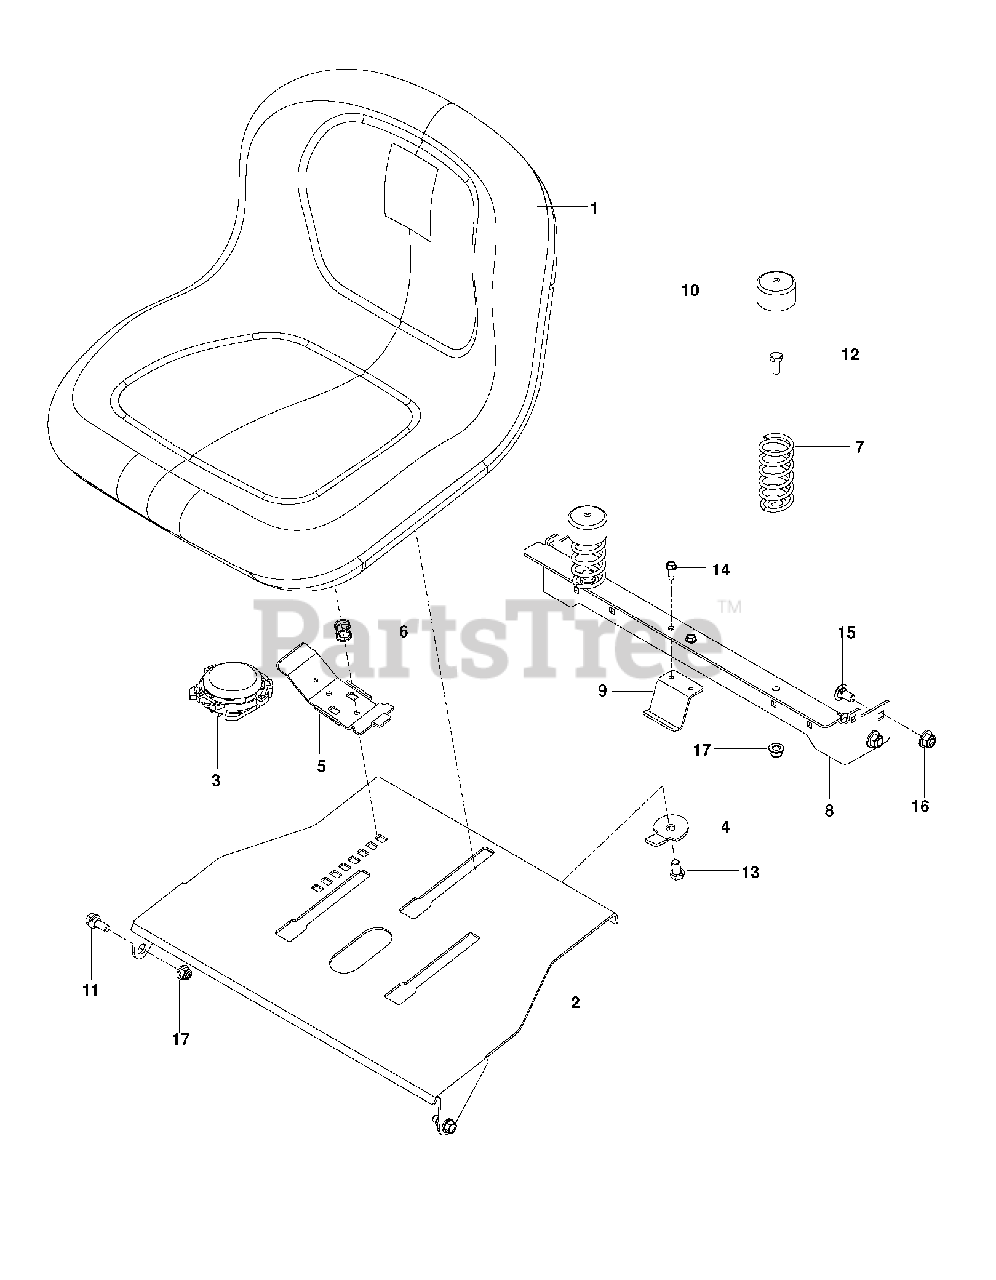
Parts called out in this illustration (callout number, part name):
1	SEAT.TH150.MS498.GRY.HUSQ.TEX
2	PLATE, SEAT, ORG
3	SWITCH, SEAT N/C
4	STOP, SEAT, BLACK
5	HANDLE.SLIDE.SEAT.TEX.BLACK
6	SPRING.LATCH.SEAT.TEX
7	SEAT SPRING
8	SEAT SUPPORT, REAR ORG
9	HOLDING DEVICE, FUEL TANK, BLK
10	SPRING CAP
11	BOLT, SHOULDER
12	HCS 5/16C X 3/4
13	HCS 3/8-16 X 5/8 GR 5 ZD
14	SCREW 1/4 X 5/8
15	RHSNB 3/8-16 X 3/4 GR5 ZD
16	NUT 3/8-16 HEX FLG NYLOC ZD
17	5/16-18 NYLOC FLANGE NUT
